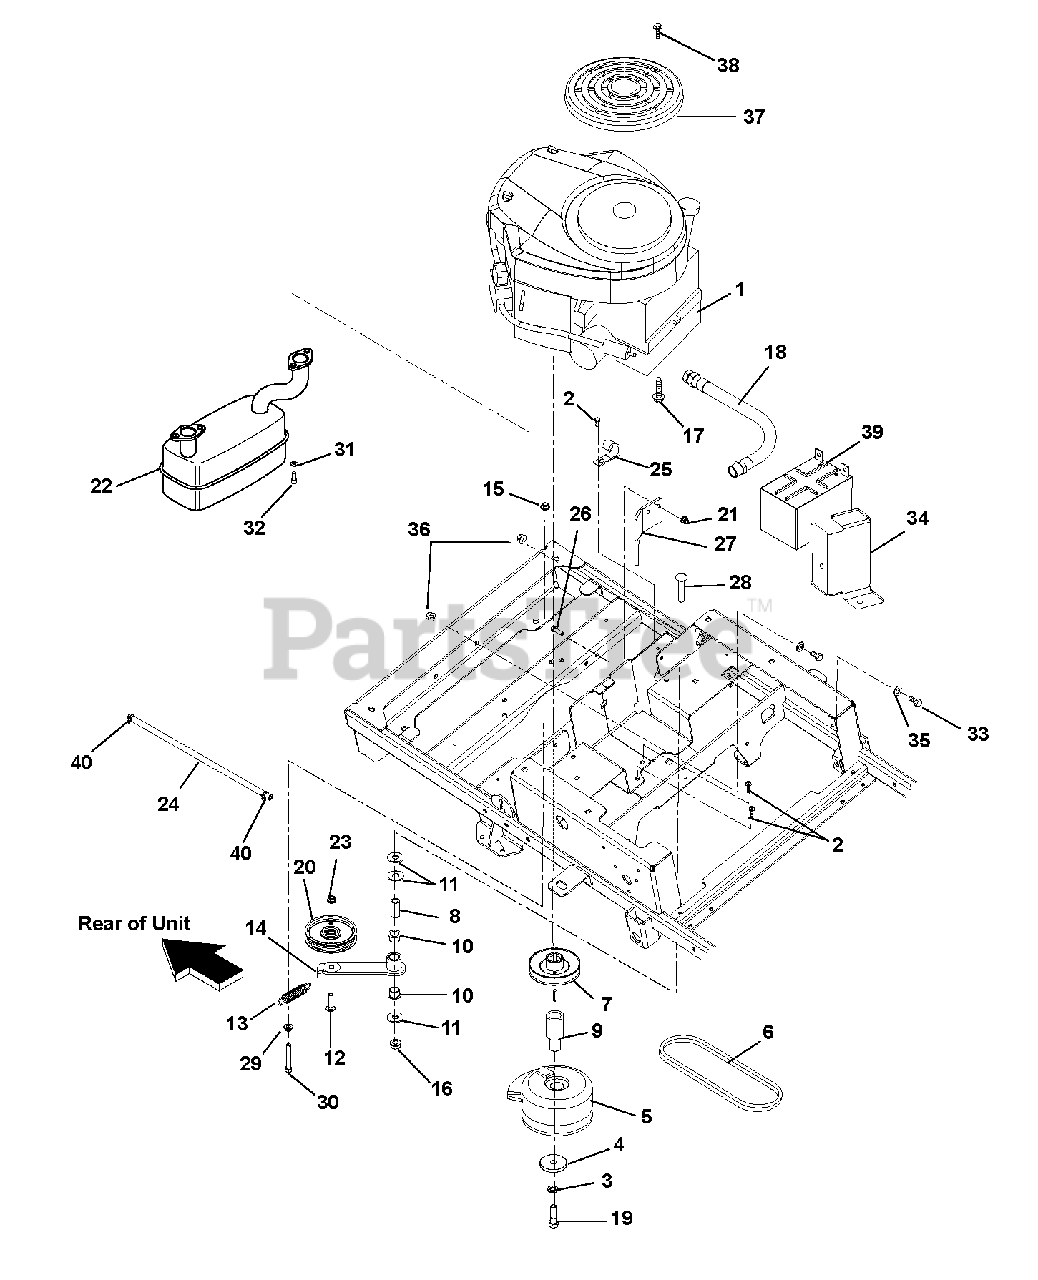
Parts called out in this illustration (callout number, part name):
1	Engine, 18HP V-Twin CE
2	Screw, Tapping .250-20 x .37 Hex Washer Head
3	Washer, Locking .44 x .109 Regular
4	Washer, Flat Steel .469 x 2.00 x .25
5	Clutch, MS with Brake
6	Belt, HA 62.50 Wrapped
7	Pulley, V 4.5 x 1.5 AB Section with Key
8	Bushing, Sleave .500 x .750 x .1.560
9	External, Crankshaft Lower
10	Bushing, Flange 0.75 x 0.875 x .625 x 1.125
11	Washer, Flat Steel .563 x 1.38 x .109
12	Bolt, Round Head Square Neck .38-16 x 1.50 Grade 5
13	Spring, Tension .105 x .812 x 3.88
14	Weldment, Ground Drive Idler Arm
15	Nut, 3/8-16 Flange Nyloc
16	Nut, Locking Top Flange .50-13
17	Screw, Tapping .38-16 x 1.00 Hex Washer Head
18	Hose Assembly, Oil Drive .38 x 11.5 OAL
19	Bolt, Hex .44-20 x 4.50 Grade 8
20	Assembly, 4" Idler
21	Nut, .31-18 Nyloc Flange
22	Muffler, Briggs & Stratton Twin
23	Nut, Locking Top Flange .38-16
24	Fuel Hose
26	Bolt, Hex .31-18 x 1.00 Grade 5
27	Clutch Stop
28	Bolt, Round Head Square Neck .50-13 x 2.50 Grade 5
29	Nut, Flange .375-16
30	Bolt, Hex .38-16 x 2.50 Grade 5
31	Washer, Locking .31 x .078 Regular
32	Screw, Cap .31-18 x .75
33	Bolt, Hex .25-20 x .75
34	Bracket, Battery Hold Down
35	Washer, Flat Steel .281 x .62 x .065
36	Nut-KEPS .250-20
37	Guard, Briggs & Stratton Engine
38	Screw, 8-16 x .87
39	Battery, 12V, 215 CCA, GEP
40	Clamp, Fuel Line
